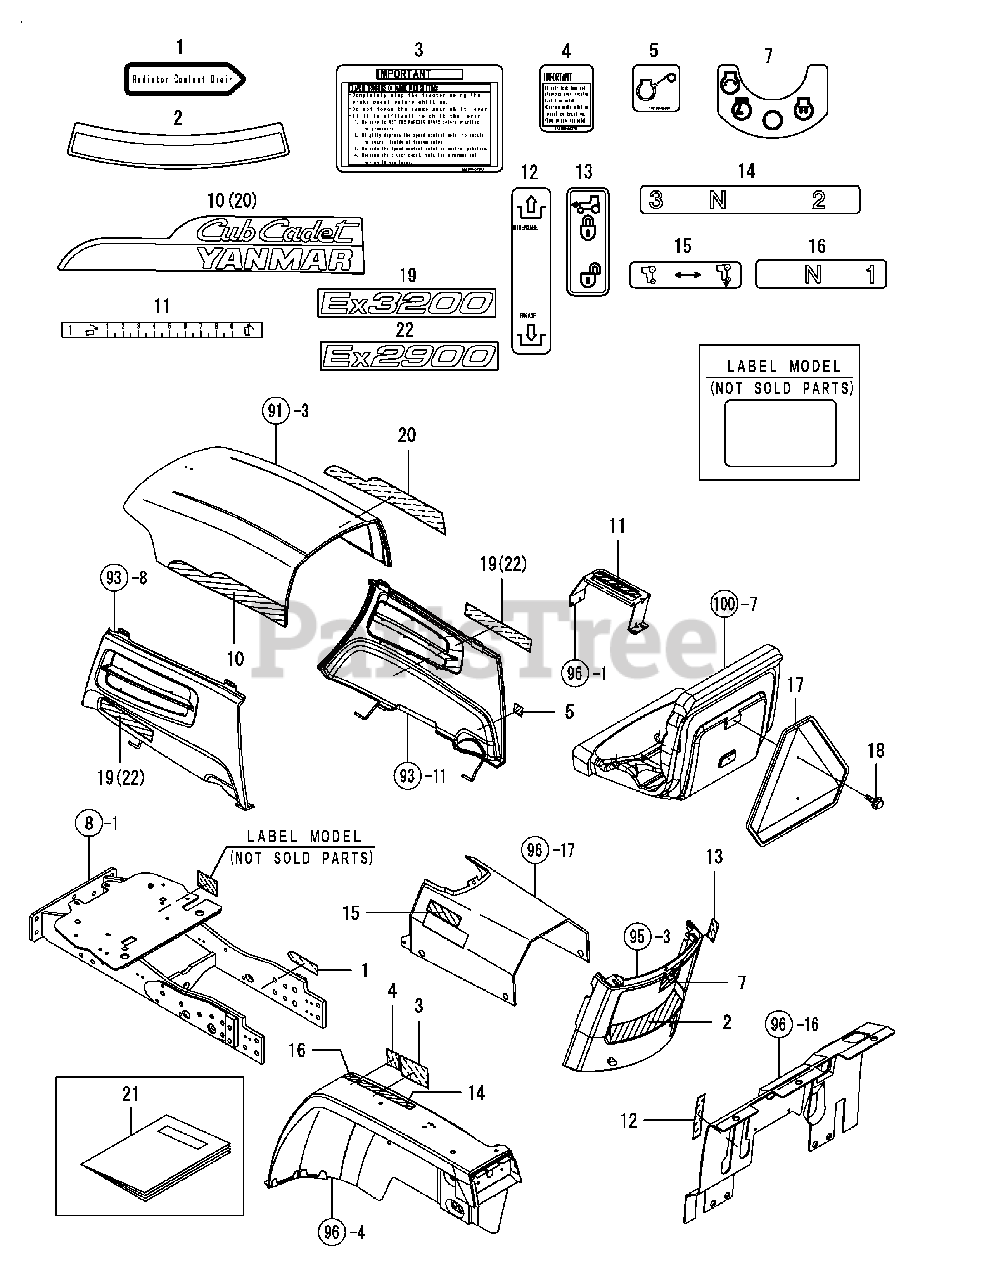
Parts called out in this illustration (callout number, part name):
2	DECAL, COLD START
3	LABEL, IMPORTANT, SHIF
4	LABEL, IMPORTANT, DIFF
6	LABEL, SCV LEVER
7	LABEL, START SWITCH
8	LABEL, SCV LOCK
9	LABEL, SCV COUPLER
14	LABEL, RANGE2-3
17	EMBLEM, SMV CMP
18	BOLT M 6X 20 PLATED
21	OPERATOR'S MANUAL
22	LABEL, MODEL EX2900
